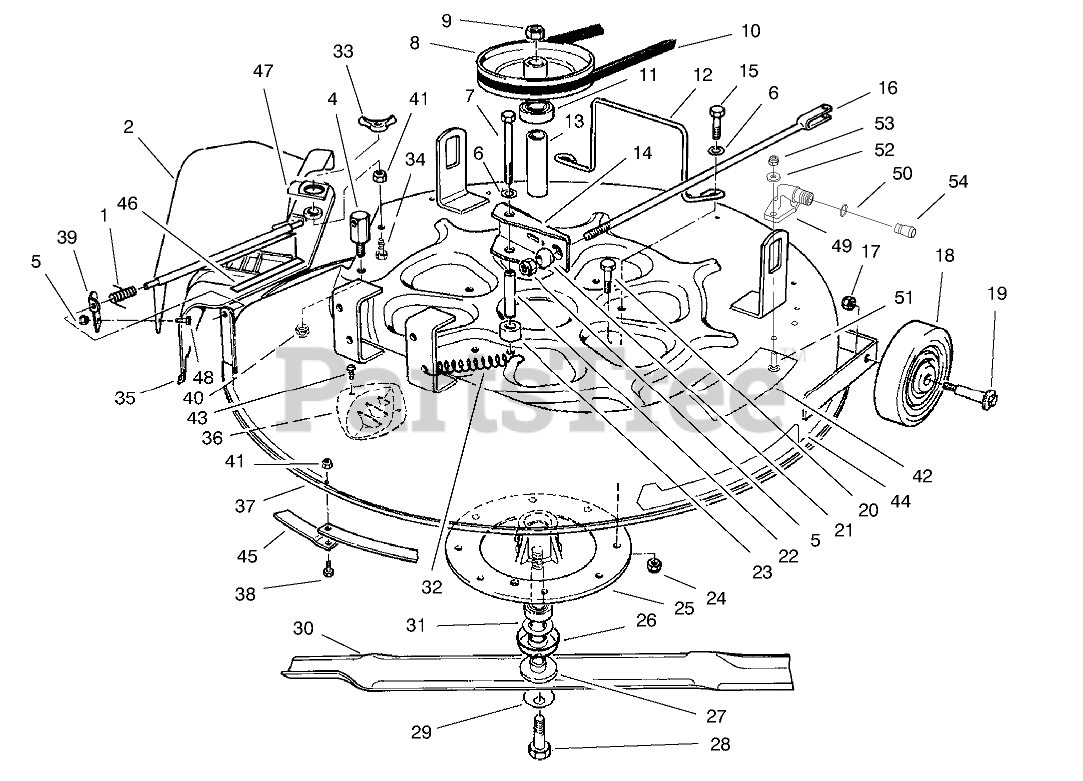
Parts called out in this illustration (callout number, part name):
1	SPRING
2	Deflector
4	POST-PIVOT
5	NUT-HEX
6	WASHER-PLAIN
7	SCREW-HH
8	PULLEY-DECK
9	NUT-HEX
10	V-BELT
11	BEARING-BALL
12	GUIDE-DECK BELT
13	SPACER-BEARING
14	Assy.-Brake, Deck
15	SCREW-HH
16	DECK BRAKE ROD WA
17	NUT-LOCK, NI
18	WHEEL-DECK
19	BOLT-WHEEL
20	SCREW-HH
21	BALL-SWIVEL, STOP
22	POST-BRAKE MTG
23	SPACER-DECK BRAKE
24	NUT-LOCK, NI
25	CASTING-SPINDLE
26	SHIELD-BEARING
27	SHAFT-SPINDLE
28	SCREW-HH
29	WASHER-BELLEVILLE
30	Blade
31	SPACER
32	SPRING-EXTENSION
33	Nut-Wing
34	SCREW-HHF
35	COVER- 25" (W/KICKER)
36	KICKER
37	Deck (Incl. Ref. #42 & 46)
38	SCREW-HH
39	BRACKET-DEFLECTOR
40	NUT-LOCK, NI
41	NUT-LOCK, NI
42	DECAL - DANGER
43	SCREW-PPH
44	DECAL - RECYCLER 25"
45	25" RECYCLER RING (BLACK)
46	DECAL-DANGER, DEFLECTOR
48	SCREW-HH
49	FITTING-WASHOUT
50	O-RING
51	BOLT-CARR
52	WASHER-FLAT
53	NUT-LOCK, NI
54	CONNECTOR-HOSE
